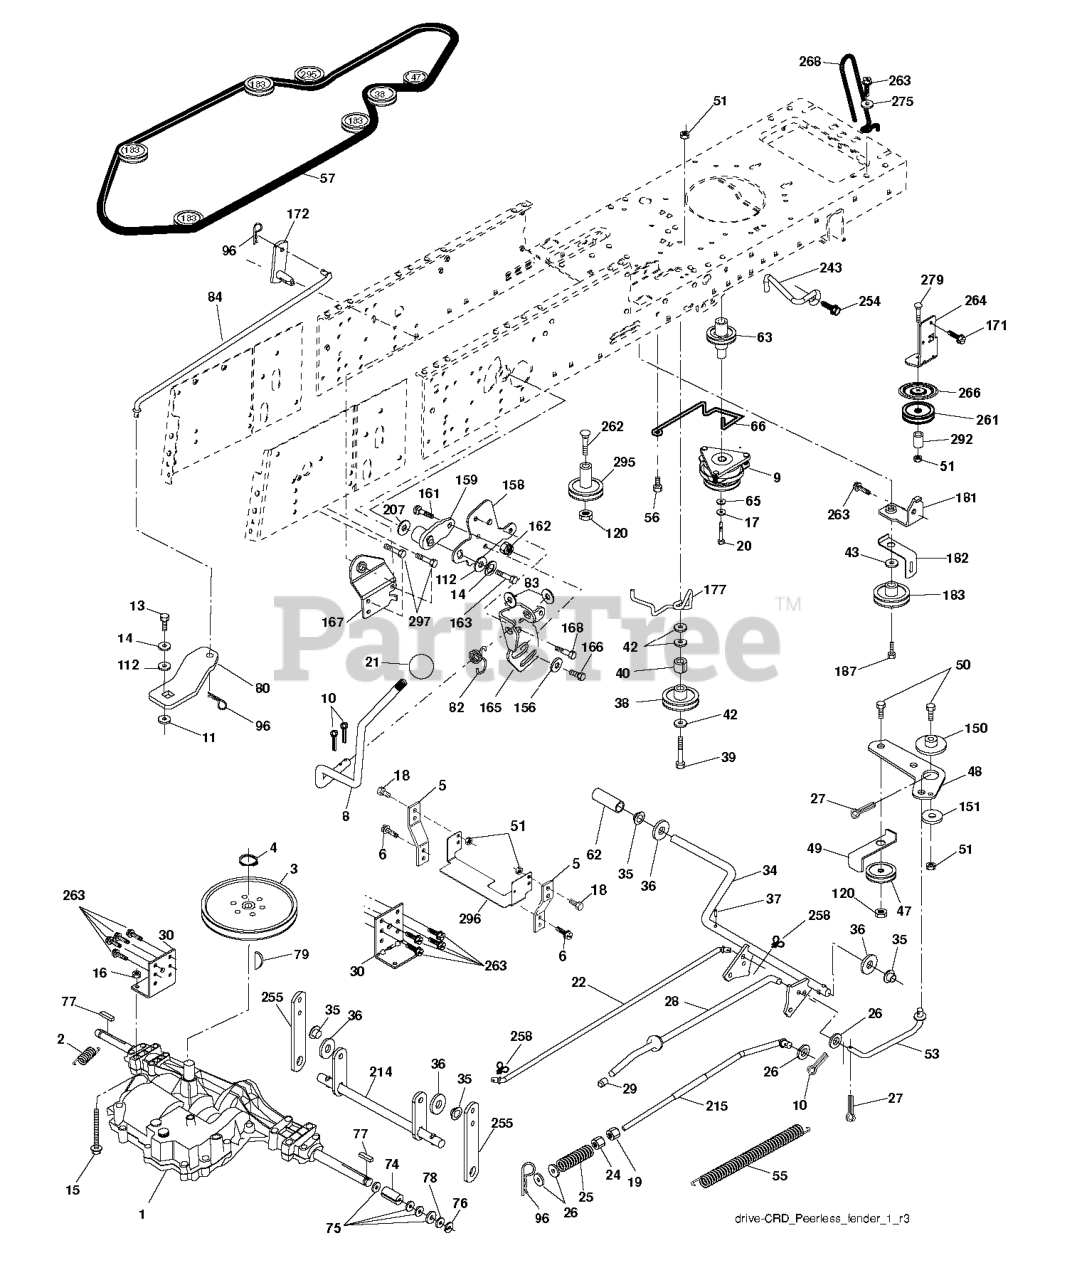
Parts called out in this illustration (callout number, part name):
1	TRANSAXLE (206-546) 6SP.CRD
2	SPRING,BRAKE RETURN
3	PULLEY
4	RETAINING RING LT
5	STRAP TORQUE
6	SCREW 5/16"
8	ROD SHIFT FENDER ADJUST LT
9	CLUTCH.ELECTRIC.OGURA.EURO.
10	PIN COTTER
11	WASH-SHFT PLT LT
13	BOLT 1/4-28X3/4
14	LOCKWASHER
15	BOLT HEX 5/16-18 GR 5
16	NUT.71038.31-18.HEX.NYLOCK
19	NUT
20	BOLT HEX 7/16-20X4-1/4"
21	KNOB.DUCKHEAD.1/2
22	ROD
24	NUT
25	SPRING ROD LT
26	WASHER
27	COTTER PIN
28	ROD, PARKING BRAKE
29	CAP
30	BRKT, MOUNT TRNSAXLE
34	SHAFT, FOOT PEDAL
35	BEARING.NYLON
37	DRIVE PIN
38	PULLEY.FLAT
42	WASHER
47	IDLER PULLEY
48	BELLCRANK, CLUTCH
49	RETAIN BELT
50	BOLT.3/8-16X1.50
53	LINK.CLUTCH.7.66.2005
55	SPRING, RETURN LT
56	SCREW.3/8-16
57	V-BELT.KEV.111"
62	PEDAL COVER T
63	PULLEY.ENGINE.CVX.LT
65	LOCKWASHER
66	KEEPER BELT ENGINE
74	SPACER AXLE
77	SQUARE KEY
79	KEY STD (1373) DANA
82	SHIFT SPRING
83	WASHER
96	RETAINER M
120	NUT LOCK FLG 3/8-16 UNC
150	BUSHING.BELLCRANK.GRD.DR
151	WASHER 12/32X2X10GA
156	WASHER.SRRTD.5/16
158	BRACKET
159	RB HUB.SHIFT
161	BOLT
162	NUT.CROWNLOCK.1/4
165	RP BRACKET
166	CAPSCREW.HXHD.FLG.5/16-18X.625
167	BRACKET.SUPT.SHIFT.CRD
168	BOLT.SHOULDER.5/16-18X
172	SHAFT
181	BRACKET
182	BELT GUIDE
183	PULLEY.V-IDLER.
187	BOLT.5/16-18X1.25
207	WASHER NYL
214	LEVER
243	BRACKET, ANTI-ROTATION
254	SCREW 3/8-16X1
255	SHAFT
258	CLIP RETAINER
261	FLAT IDLER PULLEY
263	SCREW, 3/8-16X3/4
264	BRACKET.IDLER
266	PROTECTOR
268	GUARD MUFFLER
275	WASHER
292	SPACER
295	PULLEY IDLER COMPOSITE
297	SCREW LT.3/8-46X5/8
